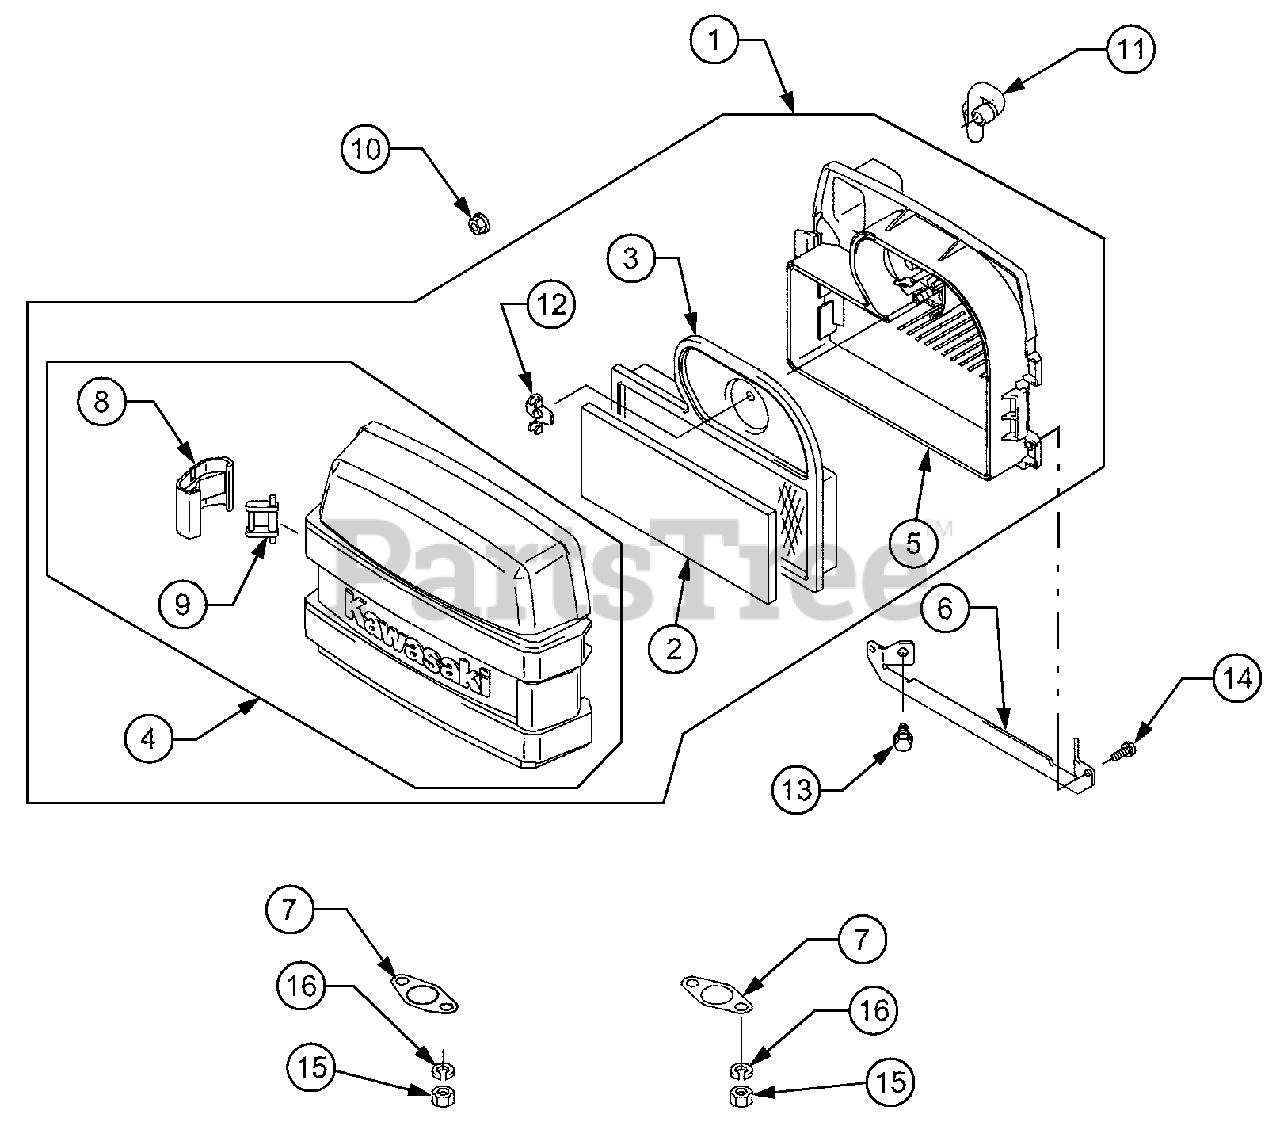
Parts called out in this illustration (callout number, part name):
1	Filter Assy, Air
2	Element, Air Filter
3	Element, Air Filter
4	Case Assy, Air Filter
5	Case Assy, Air Filter
7	Gasket, Muffler
8	Hook, Air Filter
9	Joint
10	Nut
13	Bolt, Flanged
14	Screw, Pan-ws+-
15	Nut, Hex - Small
16	Washer, Spring
